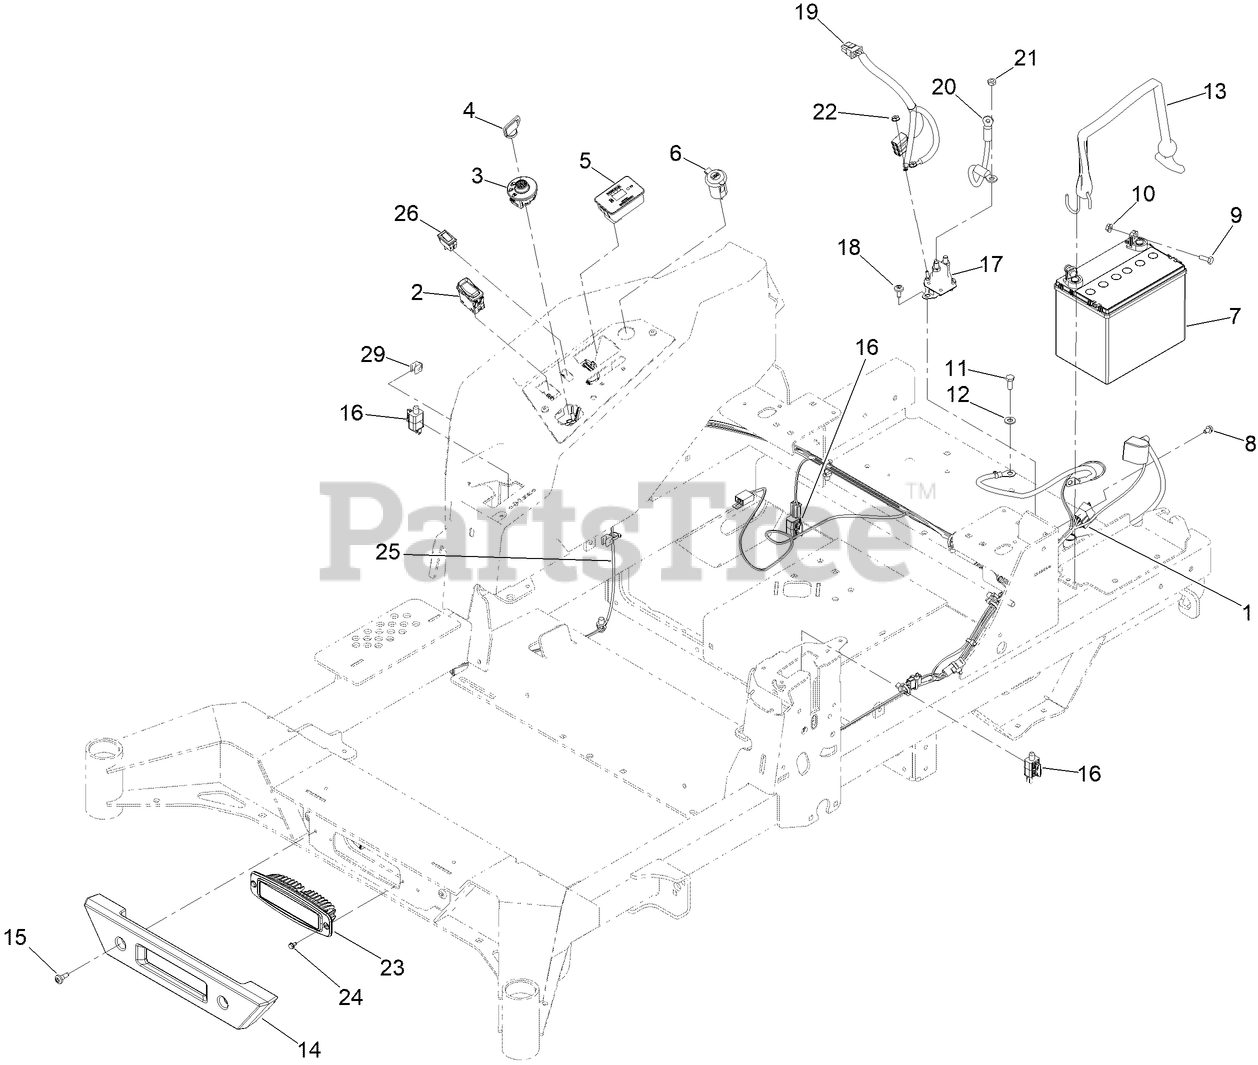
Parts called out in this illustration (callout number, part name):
1	HARNESS-WIRE, ZMASTER
2	SWITCH-ROCKER, ON-NONE-ON
3	SWITCH-IGNITION
4	KEY-IGNITION
5	MODULE ASM
6	PORT-POWER, USB
7	BATTERY-DRY
8	SCREW-HWH
9	SCREW-HH
10	NUT-HF
11	SCREW-HH
12	WASHER-PLAIN
13	STRAP, BUNGEE
14	BUMPER-FRONT
15	SCREW-SHOULDER
16	SWITCH
17	SOLENOID
18	SCREW-TORX
19	ADAPTER-HARNESS, WIRE
20	CABLE-BATTERY, POSITIVE
21	NUT-JAM
22	NUT-KEPS
23	MOUNT-FLUSH, LIGHT
24	SCREW-HWH
25	HARNESS-WIRE, LIGHT KIT
26	SWITCH-ROCKER
29	CLIP-EDGE W/TIE, PERPENDICULAR
99	KEYS-IGNITION (SPARE PAIR)
